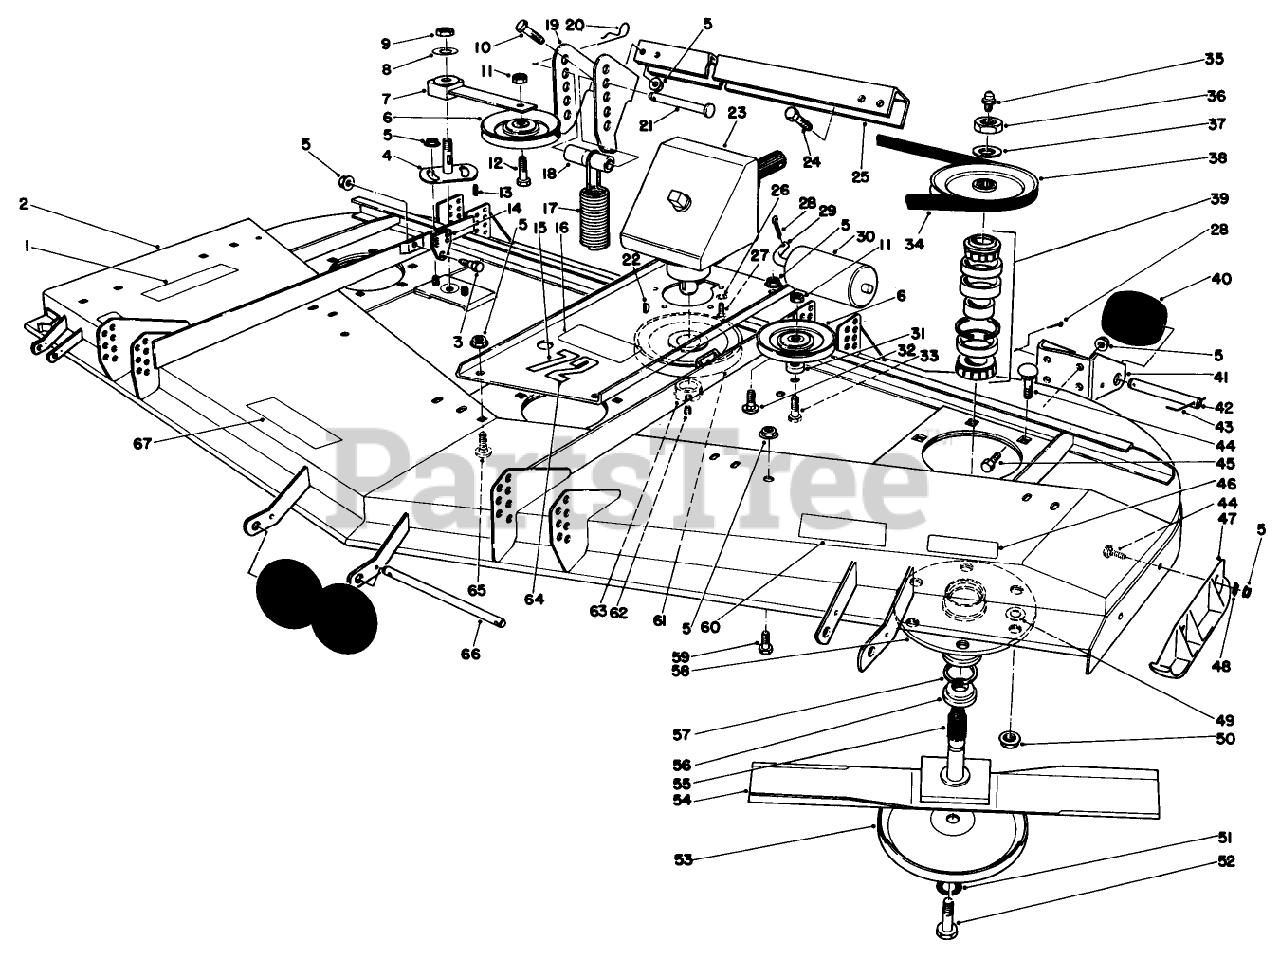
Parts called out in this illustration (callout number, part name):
1	DECAL-CAUTION, DEFLECTOR
2	Housing
3	BOLT-SHOULDER
4	PLATE-IDLER
5	NUT-HHF, WHIZ
6	Pulley
7	IDLER ARM ASM
8	WASHER-FLAT
9	NUT-LOCK, NI
10	SCREW-HH
11	NUT-HEX
12	SCREW-HH
13	KEY-SQUARE
14	SPRING END R
15	GEARBOX BASE R
16	Decal-Caution
17	Spring-Extension
18	SPACER
19	SPRING BRACKET R
20	PIN-HAIR
21	PIN-CLEVIS
22	KEY-WOODRUFF
23	GEAR BOX ASM
24	SCREW-HH
25	Adapter-Spring Bracket
26	WASHER-LOCK
27	SCREW-HSH
28	PIN-COTTER
29	SHAFT-ROLLER, REAR
30	ROLLER-DECK
31	SPACER
32	SCREW-CARR
33	SCREW-HH
34	V-BELT (72)
35	FITTING-GREASE
36	NUT-HEX
37	WASHER
38	PULLEY & HUB ASM, WELDED
39	BEARING ASM
40	ROLLER
41	Bracket-Roller
42	SHAFT-ROLLER
43	PIN-SPECIAL
44	SCREW-CARR
45	SCREW-HH
46	DECAL-CAUTION, BLADE
47	Skid
48	LOCKWASHER-PYRAMID
49	WASHER-FLAT
50	NUT-HF
51	WASHER-LOCK
52	SCREW-BLADE
53	Cup-Scalp
54	Blade
55	SHAFT
56	SPACER
57	SEAL-OIL
58	Housing-Spindle
59	SCREW-HH
60	REAR WEIGHT DECAL
61	PULLEY WA BO
62	SCREW-SET, HSH
63	BUSHING-LOCK, TAPER
64	DECAL
65	SCREW-CARR
66	SHAFT-ROLLER
67	CAUTION DECAL
